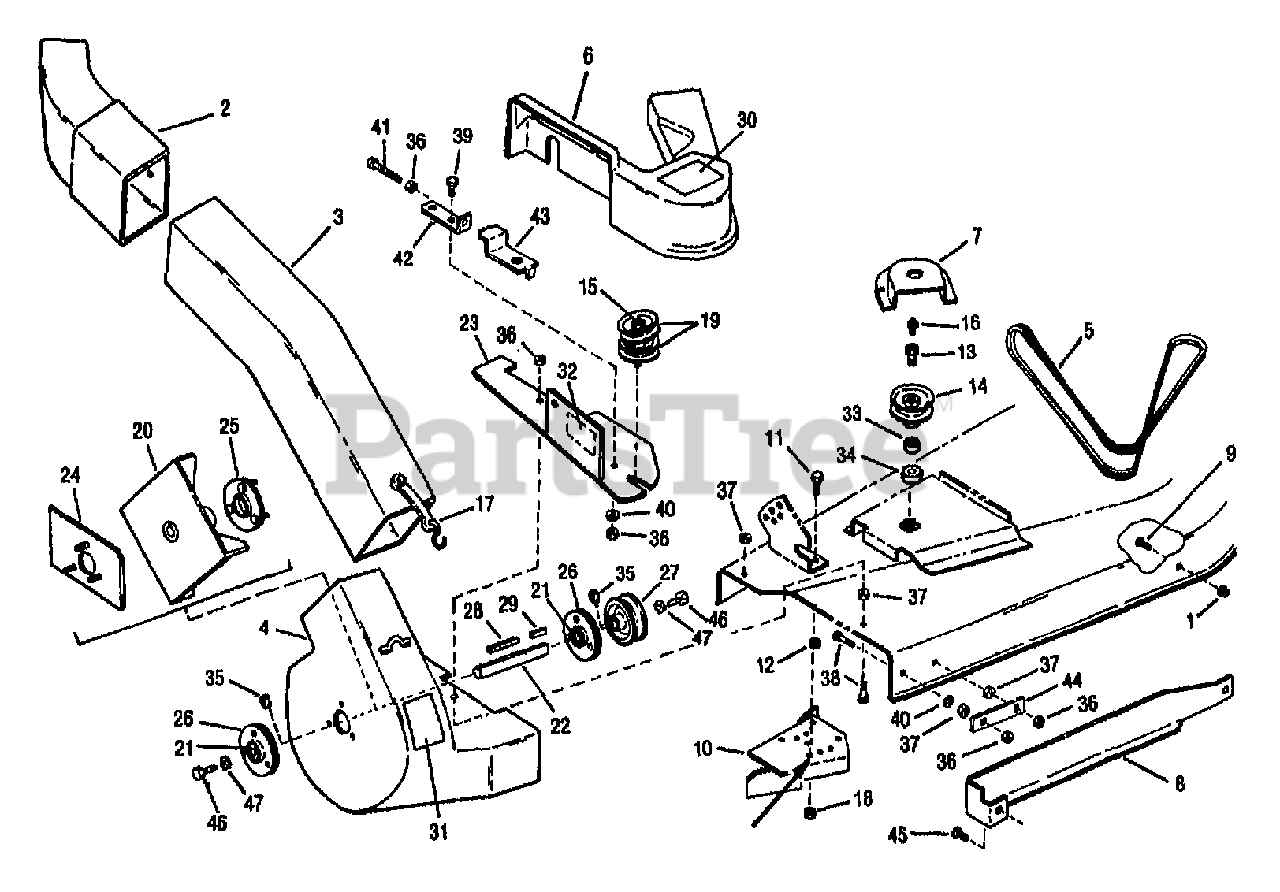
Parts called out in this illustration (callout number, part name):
1	NUT-HFLK 5/16-18 ZP
2	CHUTE-UPPER ELBOW
3	TUBE-LONG
4	HOUSING
5	BELT-V
6	GUARD-BELT
7	GUARD-BELT
8	BAFFLE-LONG
9	SCR-CARR 5/16-18X.62 G2 ZP
10	ASSM-BAFFLE
11	SCR-HH 3/8-16X1.25
12	NUT-HEX/JAM 3/8-16
13	LOCK-SHEAVE
14	PULLEY-DRIVE
15	SHAFT-DOUBLE IDLER
16	FITTING-GREASE 1/4-28X2.00
17	ASSM-STRAP
18	NUT-LOCK 3/8-16
20	IMPELLER
22	SHAFT-FAN 3/4"
23	FRAME-MOUNTING
24	FLANGETTE-OUTER
25	FLANGETTE-INNER
27	SHEAVE-FAN
28	KEY-.188 SQ X 2.0
29	KEY-.187 SQ X .75
30	DECAL-DANGER
31	DECAL-DANGER
32	DECAL (MT FRAME)
33	SPACER-.625X.406X.179
34	SPACER-1.25X.781X.179
35	WASHER-THRUST
36	NUT-H/LK 5/16-18
37	NUT-HEX JAM 5/16-18
38	SCR-HFLK 5/16-18X1.00 ZP
39	SCR-HH 5/16-18X.875 G5 ZP
40	WASHER-FLAT 5/16 SAE
41	SCR-HH 5/16-18X2.75
42	ASSM-BRKT
43	BRKT-ADJUSTMENT
44	SUPPORT
45	SCR-CARR 5/16-18X1.0 G2 ZP
46	SCR-HHC 5/16-18X.75 GR 5 ZP
47	WASHER-1.25X.343X.059
